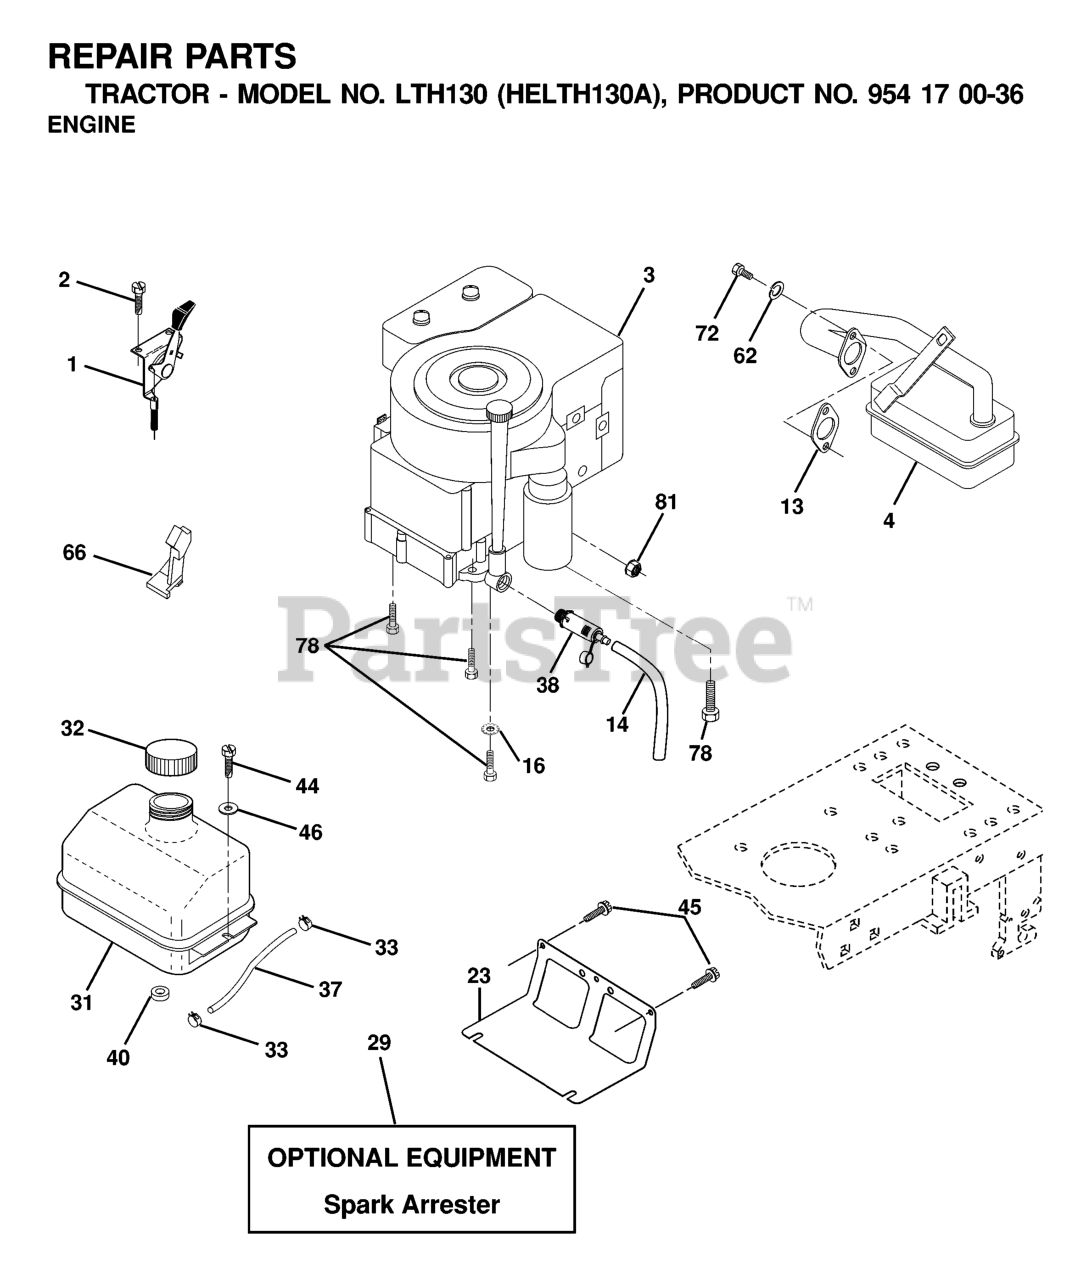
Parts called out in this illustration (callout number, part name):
1	THROTTLE.CONTROL.CABLE.BLACK
2	SCREW LT
4	MUFFLER.SINGLE.B&S.10-12HP
13	REPL BY 532 27 22-93
14	TUBE, DRAIN OIL ASM.
16	LOCKWASHER
23	SHIELD.BROWNING.DBR.GUARD
29	KIT.SPARK ARRESTOR 794945 B&S
31	TANK FUEL LT
32	FUEL CAP
33	HOSE CLAMP
37	LINE.FUEL.20
38	PLUG, OIL DRAIN EASY
40	BUSHING.SNAP.NYL.BLK.
44	SCREW HEXWSHR 1/4-20X3/4
45	SCREW, 3/8-16X3/4
46	WASHER
62	WASHER.LOCK.HVY.HLCL.SPR.5/16
66	STOP THROTTLE
72	SCREW
78	SCREW.3/8-16
81	NUT
